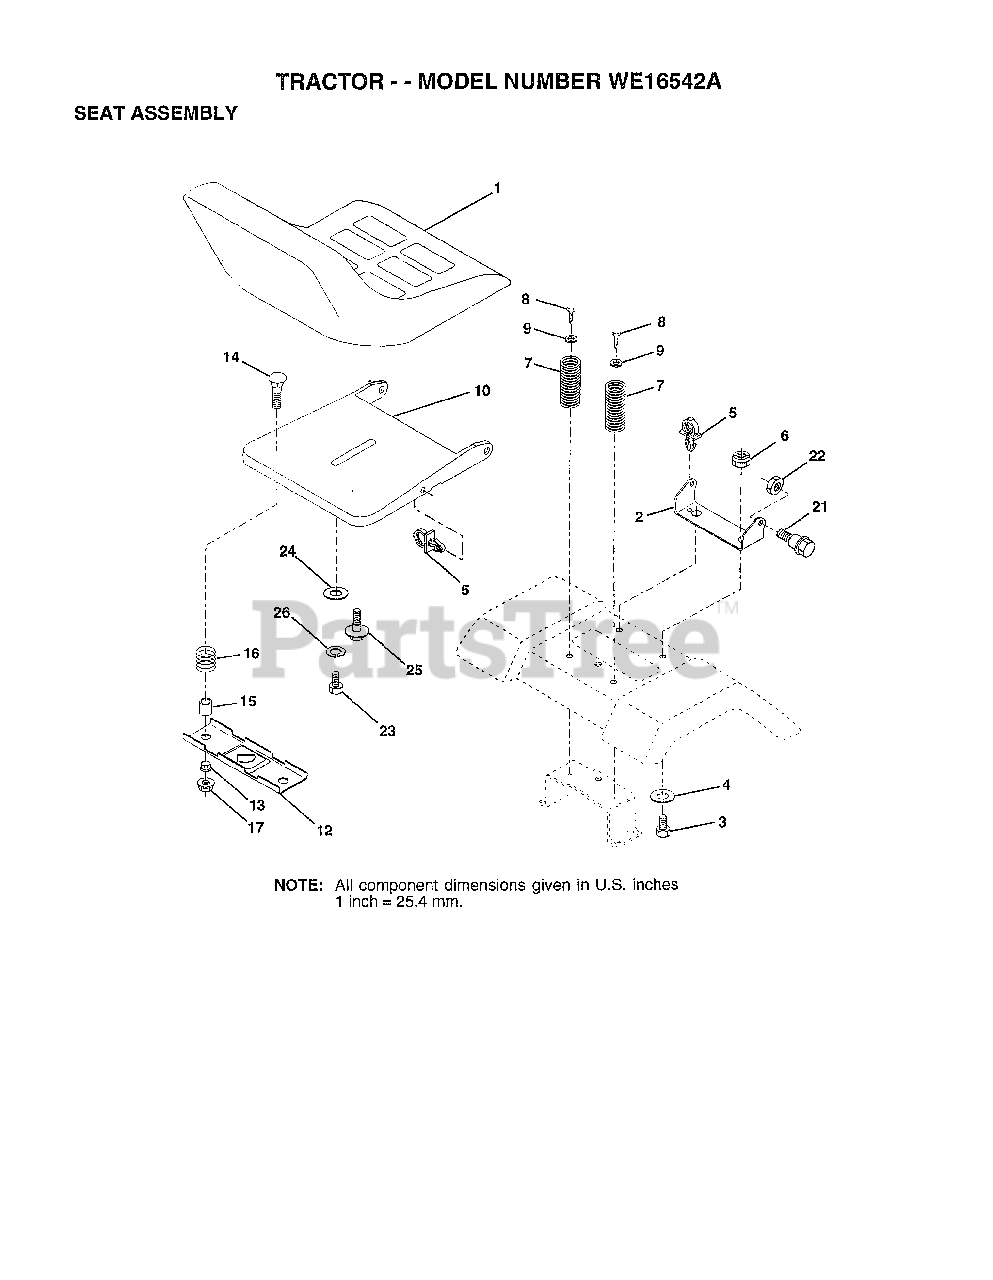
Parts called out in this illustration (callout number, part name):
2	BRACKET PVT SEAT
3	BOLT
4	WASHER PM
5	CLIP.PUSH-IN.HING
6	NUT
7	SPRING COMPRESSIO
8	SCREW GTV
9	WASHER
10	PAN-SEAT
12	BRKT SWITCH
13	BUSHING
14	BOLT-RD HD SQ NK
15	SPLIT SPACER
16	SPRING
21	"BOLT,SHOULDER"
22	NUT
23	BOLT
24	WASHER
25	"BOLT,SHOULDER"
26	LOCKWASHER
